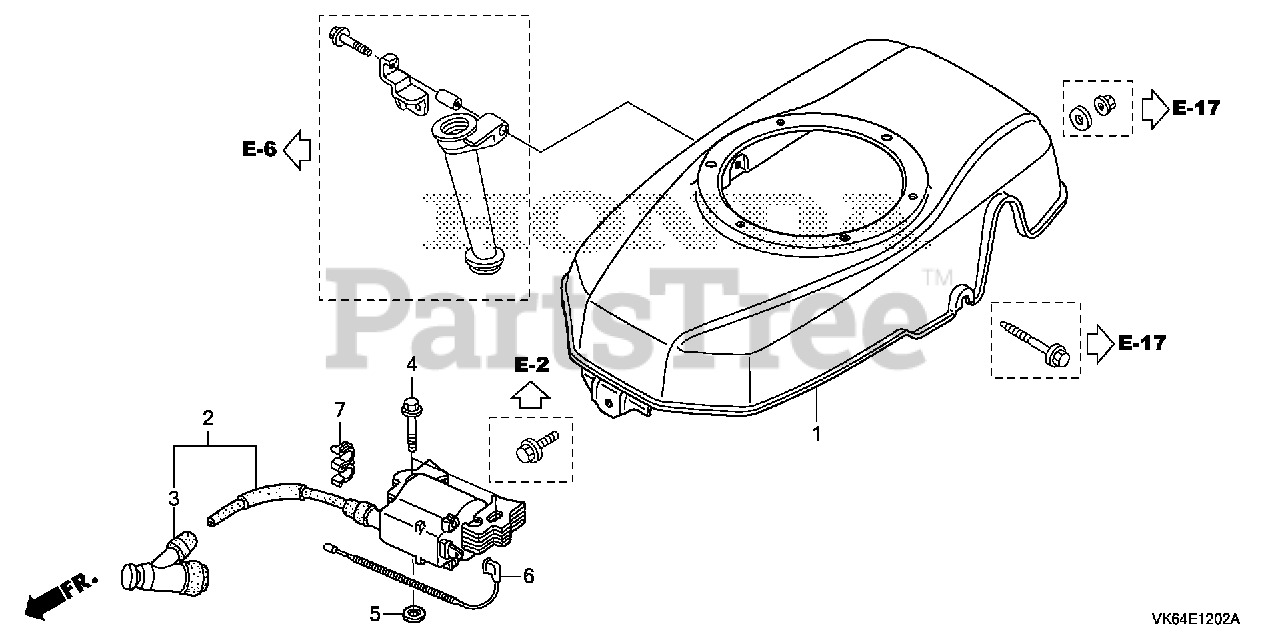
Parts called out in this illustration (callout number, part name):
1	COVER, FAN *R280* (POWER RED)
2	COIL ASSY., IGNITION & CAP ASSY. NOISE SUPPRESSOR (TOYO)
4	BOLT, FLANGE (6X28) (CT200) Use up to Engine SN 1530314.
5	WASHER, PLAIN (6MM)
6	WIRE, STOP SWITCH (BRAKE)
7	CLAMP, PIPE
